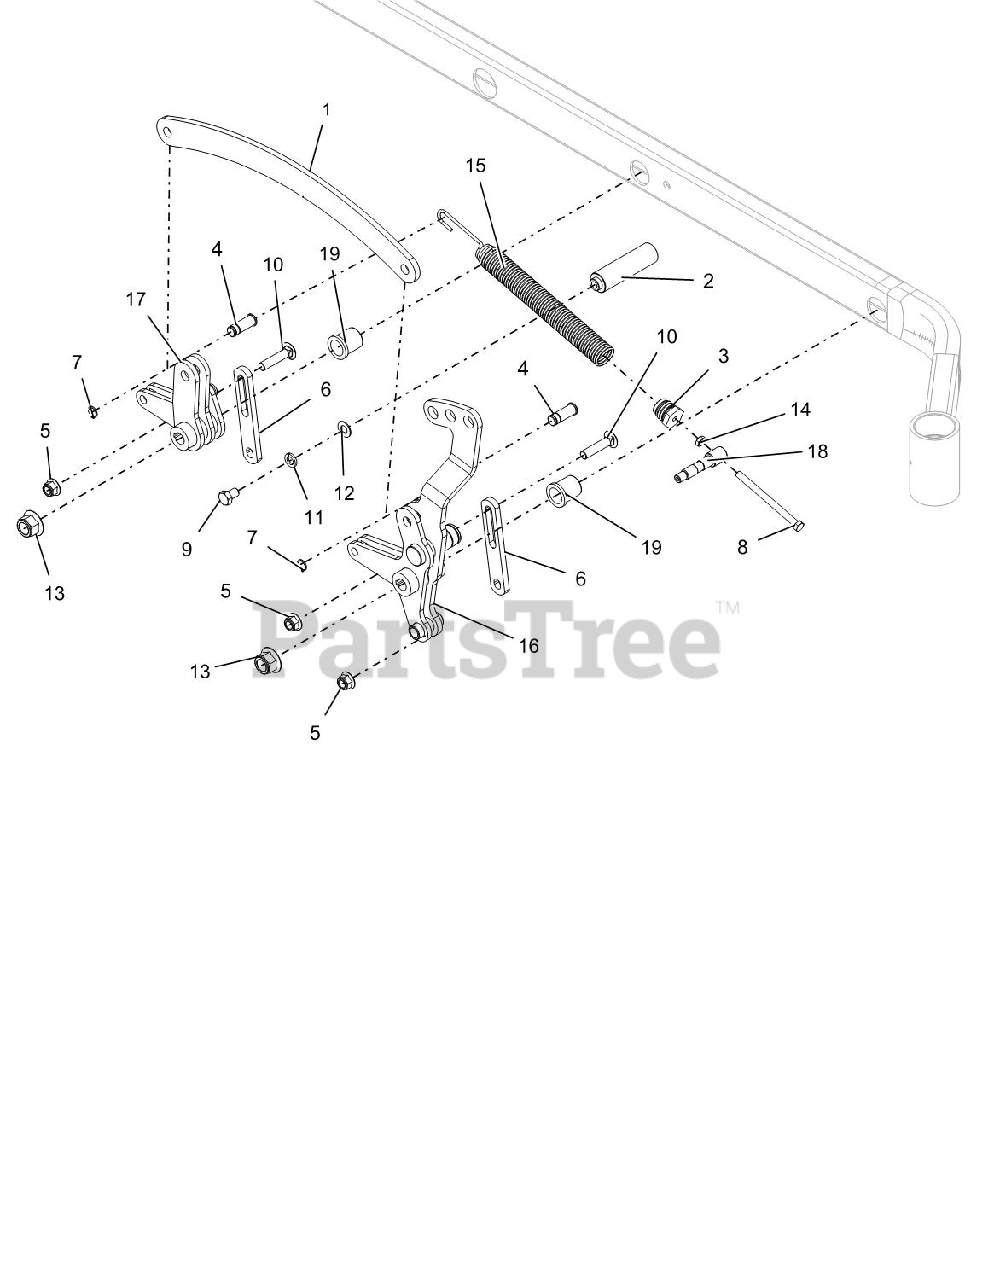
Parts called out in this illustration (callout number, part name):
1	LIFT, LINK - BLACK
2	PEDAL, LIFT
3	PLUG, SPRG
4	PIN, CLEVIS .625 SNAP RING
5	NUT-LK-NYL-FLG .50-13 YWZC
6	LINK, DECK LIFT - LONG
7	RG-RTNG-EXT .625x.050
8	BLT-HEX .38-16X5.00 GR5 YWZC
9	BLT-HEX .50-13X.75 GR5 YWZC
10	BLT-RDHDSQNK .50-13X2.25 G5 Y
11	WSHR-LK .50X.125 REG YWZC
12	WSHR-FL-STL .505X1.00X.062 YWZC
13	NUT-LK-NYL-FLG .75-10 YWZC
14	NUT, JAM .375-16 YWZC
15	SPRG, DECK LIFT
16	WLDMT, PT400 FRONT RH DECK LIFT ARM-BLACK
17	WLDMT, PT400 REAR RH DECK LIFT ARM-BLACK
18	TRUNION, SPRG
19	BSHG-FLG 1.00X1.25X1.5X1.5
